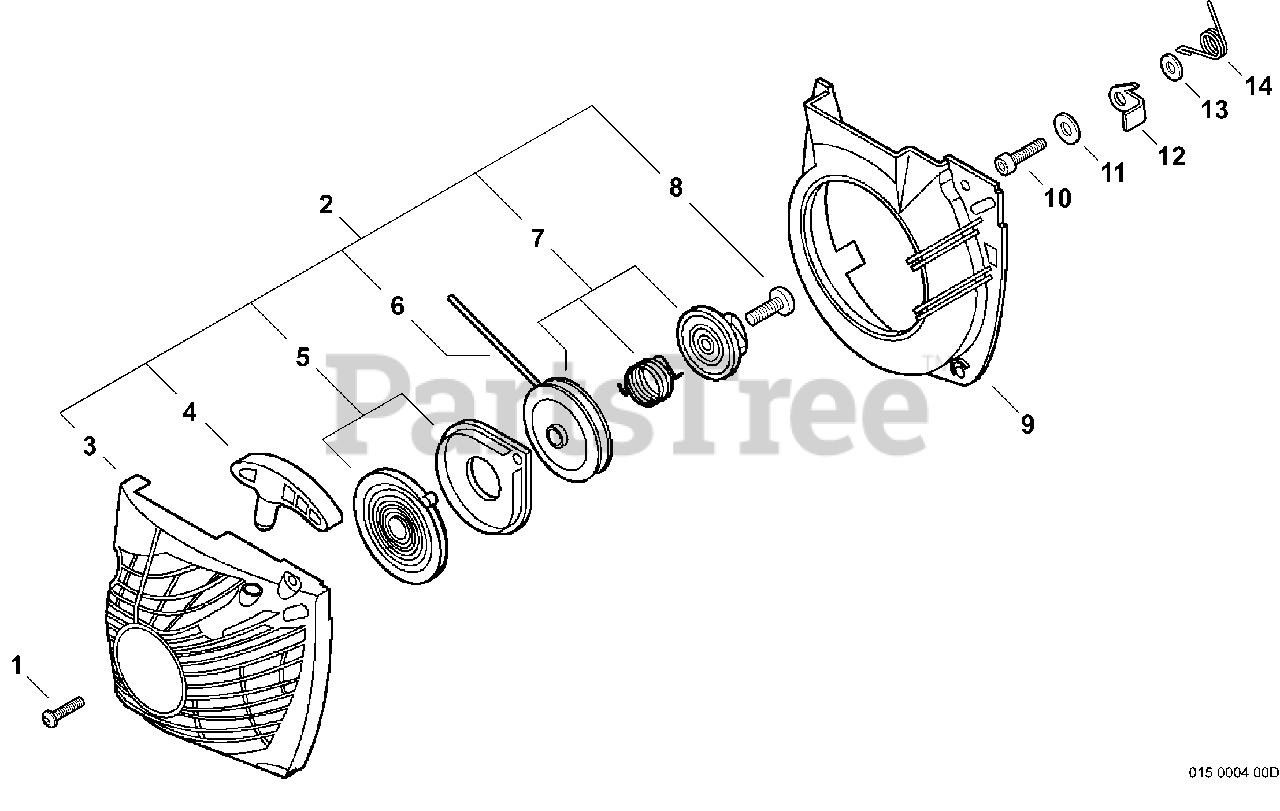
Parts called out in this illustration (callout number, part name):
1	SCREW TAPPING 5×20
2	STARTER ASSY, RECOIL - I-START
3	CASE, RECOIL STARTER
4	GRIP, STARTER
5	SPRING SET, RECOIL
6	ROPE, STARTER 3.5×900
7	REEL KIT, ROPE
8	SCREW
9	COVER, FAN
10	BOLT 5×14
11	WASHER 5.5×12×0.8
13	SPACER 5.2×8×2.1
14	SPRING, TORSION
